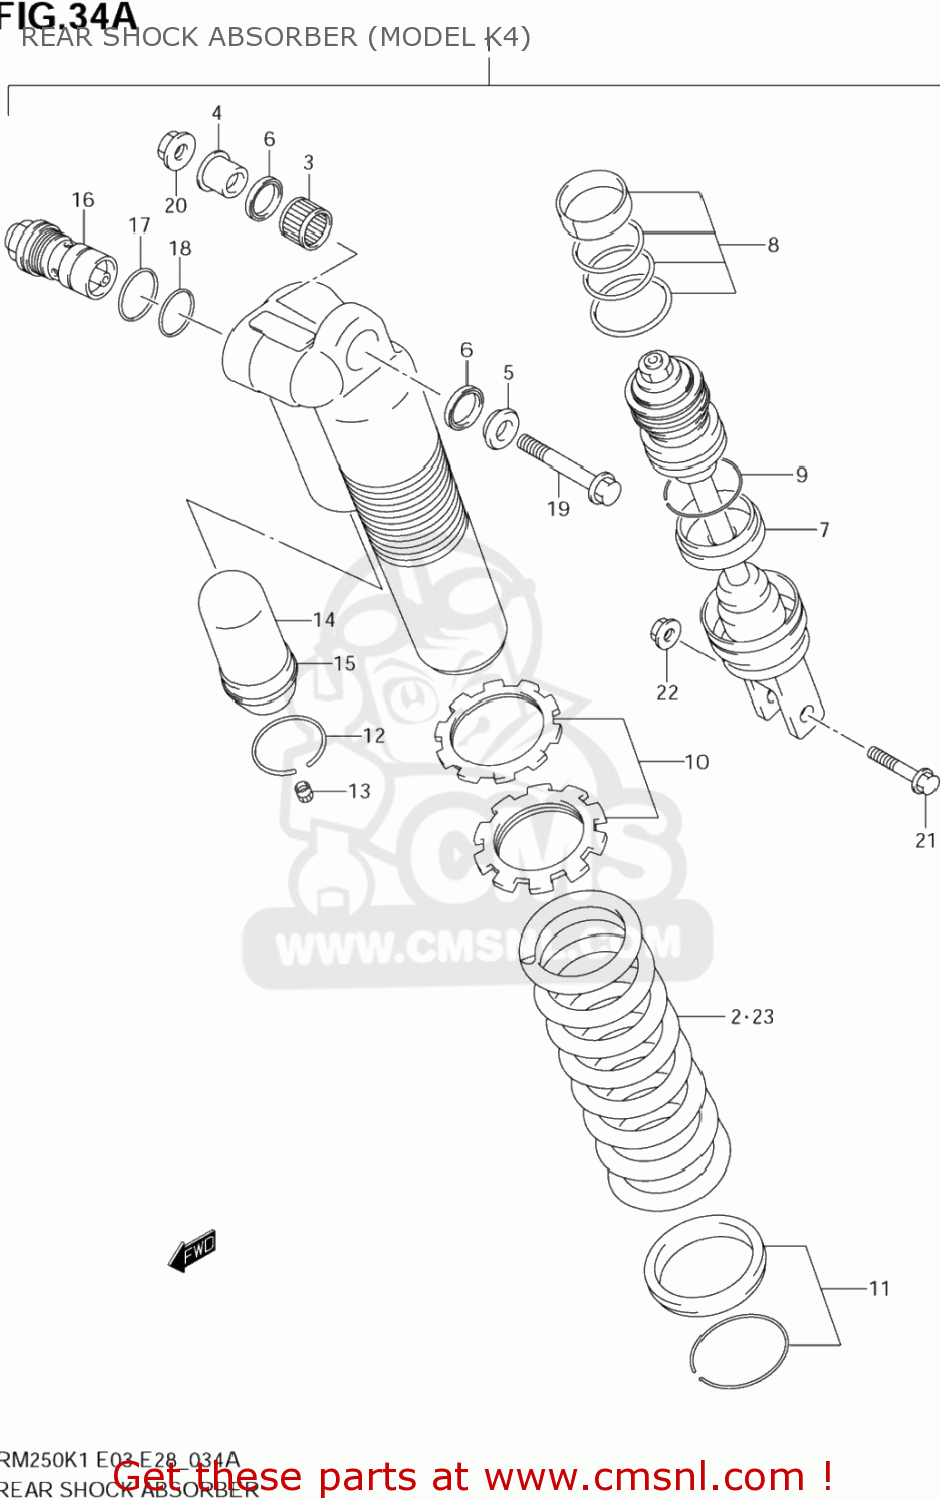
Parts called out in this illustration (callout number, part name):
1	ABSORBER ASSY,RR SHOCK
2	SPRING,RR(K=5.2)
3	BEARING(16X22X12)
4	SPACER,UPPER BRG,R
5	SPACER,UPPER BRG,L
6	SEAL,OIL(16X22X2.5)
7	ROD,PISTON
8	O RING SET
9	RING,STOPPER
10	ADJUSTER SET
11	SPRING SEAT SET
12	RING,STOPPER
13	CAP
14	BLADDER
15	CAP,CHAMBER
16	BOLT,PLUG
17	O RING
18	O RING,CTR BOLT UPR
19	BOLT(10X65)
20	NUT
21	BOLT,RR SHOCK ABSORBER LWR
22	NUT
23	SPRING,RR(SOFT K=4.8)
